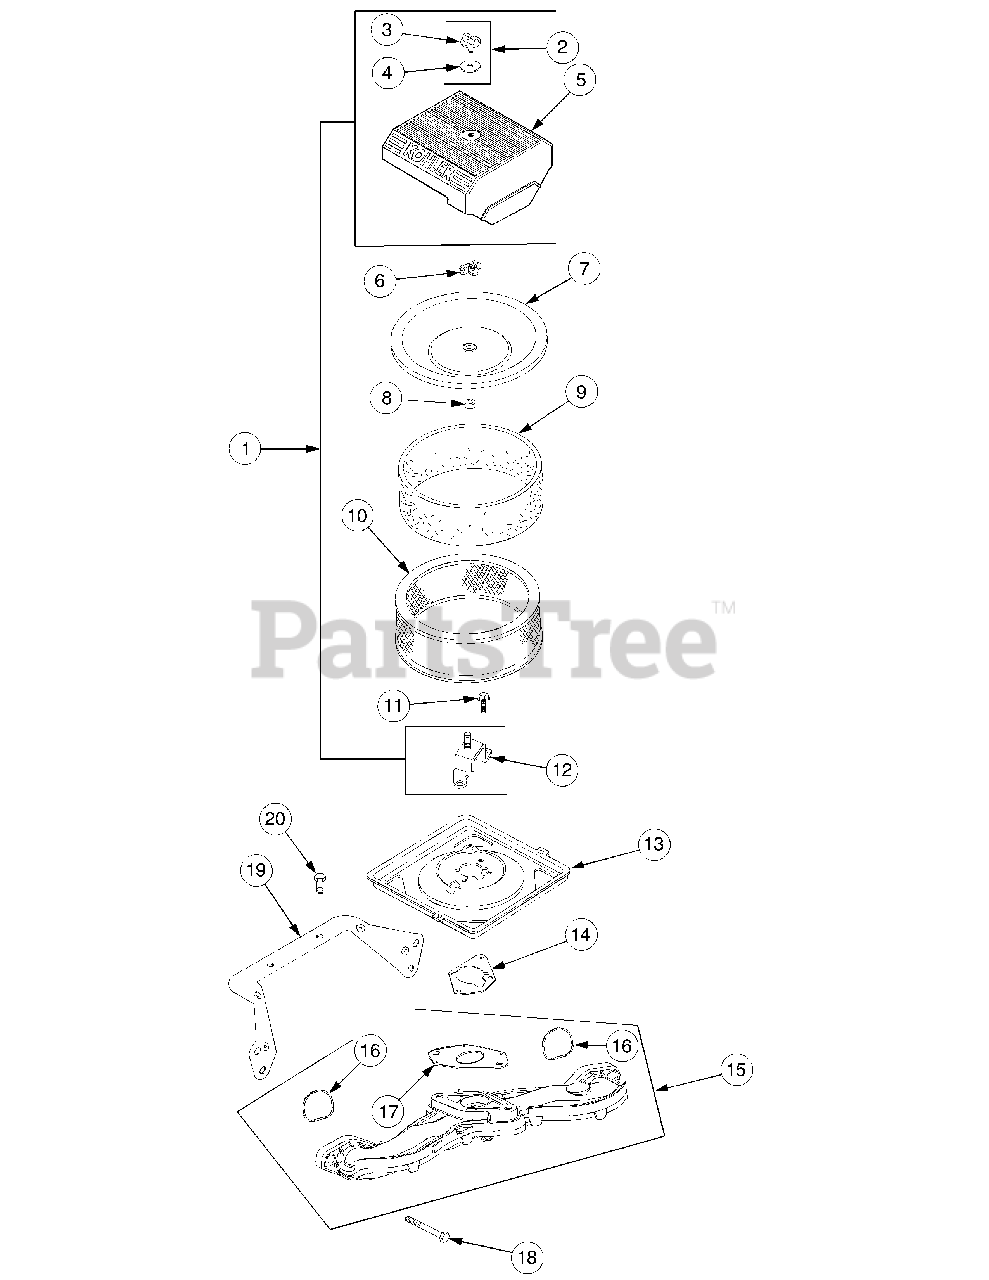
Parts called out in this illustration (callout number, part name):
1	Kit, Air Cleaner Cover (Incl. 2-5, 12)
2	Kit, Knob w/Seal (Incl. Ref #2,3)
4	Seal, Air Cleaner Cover Knob
5	Cover, Air Cleaner
7	Cover, Inner Air Cleaner
8	Seal, Inner Air Cleaner
9	Precleaner, Element
10	Element, Air Cleaner
11	Screw, Hex Flng, M6 x 1.0 x 16
12	Bracket, Air Cleaner Base
13	Base, Air Cleaner
14	Gasket, Air Cleaner Base
15	Manifold, Intake (Includes 16,17)
16	O-Ring, Intake Manifold
17	Gasket, Carburetor
18	Screw, Hex Flange, M6 x 1.0 x 40
19	Bracket, Air Cleaner Base
20	Screw, Hex Flange, M5 x .8 x10
